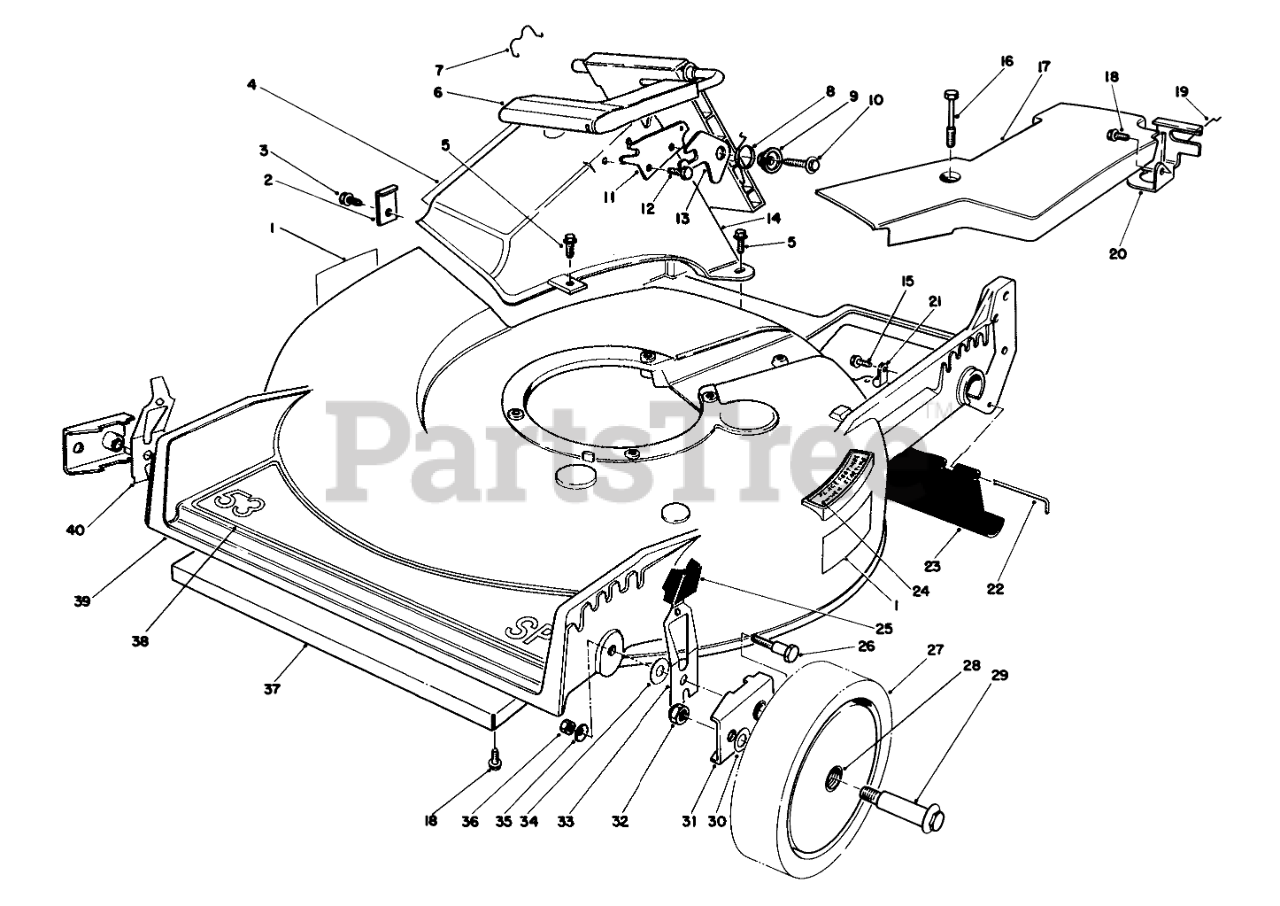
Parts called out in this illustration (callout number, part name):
1	Decal Danger
2	TUNNEL CLIP
3	SCREW
4	DECAL - DANGER
5	SCREW-HWH
6	Discharge Door Assembly
7	DOOR RET SPRING
8	TORSION SPRING
9	DOOR SPACER
10	SCREW-HWH
11	DOOR LATCH PLATE
12	SCREW-PLASTITE
13	SAFETY LATCH
14	Tunnel Discharge
15	SCREW
16	SCREW-HHFTF
17	Belt Cover
18	SCREW-HWHTF
19	RETAINER-CABLE
20	Bracket-Traction Adj.
21	CLAMP-CABLE
22	ROD-SHIELD
23	SHIELD-TRAILING
24	DECAL - STEP PAD INT'L
25	KNOB-ARM
26	PIVOT SCREW
27	Wheel & Tire Assembly (Incl. Ref. #28)
28	BUSHING
29	BOLT-WHEEL
30	WASHER
31	HP PIVOT ARM ASM
32	Nut
33	L. HP SPRING ARM ASM
34	WASHER-PIVOT
35	WASHER-BELLEVILLE
36	NUT-LOCK, NI
37	Shield-front
38	DECAL - 53 SP DECK
39	21" Housing (Incl. Ref. #1)
40	R HP SPRING ARM ASM
